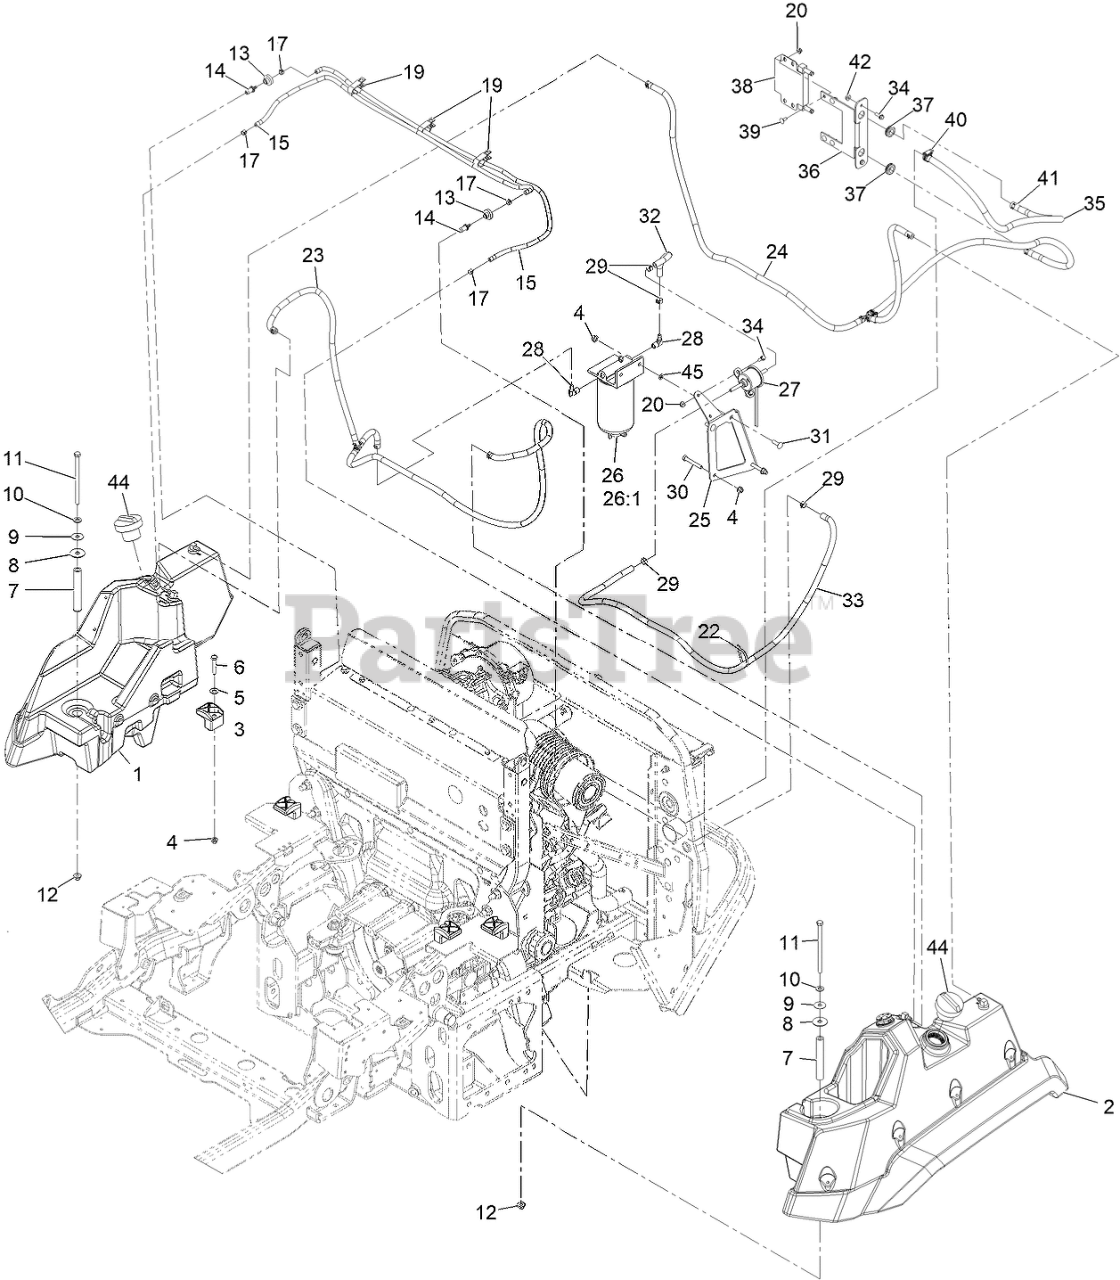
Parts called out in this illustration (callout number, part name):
1	RH FUEL TANK ASM
2	LH FUEL TANK ASM
4	NUT-HF, NI
5	WASHER-FLAT
6	SCREW-HH
7	TUBE-SPACER
8	WASHER-RUBBER
9	WASHER-PLAIN
10	WASHER-FLAT
11	SCREW-HH
12	NUT-HF, NI
13	BUSHING
14	FITTING-ORIFICE, STRAIGHT
15	HOSE-VENT, TANK
17	CLAMP-HOSE
19	CLAMP-HOSE
22	TIE-CABLE
23	FUEL SUCTION LINE ASM
24	HOSE ASM-FUEL, TEE
25	BRKT-FUEL FILTER
26	FILTER-WATER/FUEL SEPERATOR
26:1	FILTER-FUEL/WATER SEP.
27	PUMP-FUEL, ELECTRIC
28	FITTING-HYD, 90
29	CLAMP-HOSE
30	SCREW-HH
31	SCREW-CARR
32	HOSE-FUEL
33	HOSE-FUEL
34	SCREW-HWH
35	HOSE-FUEL
36	MOUNT-COOLER, FUEL
37	GROMMET
38	COOLER-OIL
39	SCREW-CARR
40	Clamp-Hose
41	CLAMP-HOSE
44	CAP-FUEL, DIESEL (ULTRA LOW SULFUR)
45	RING-RETAINING, BOLT
